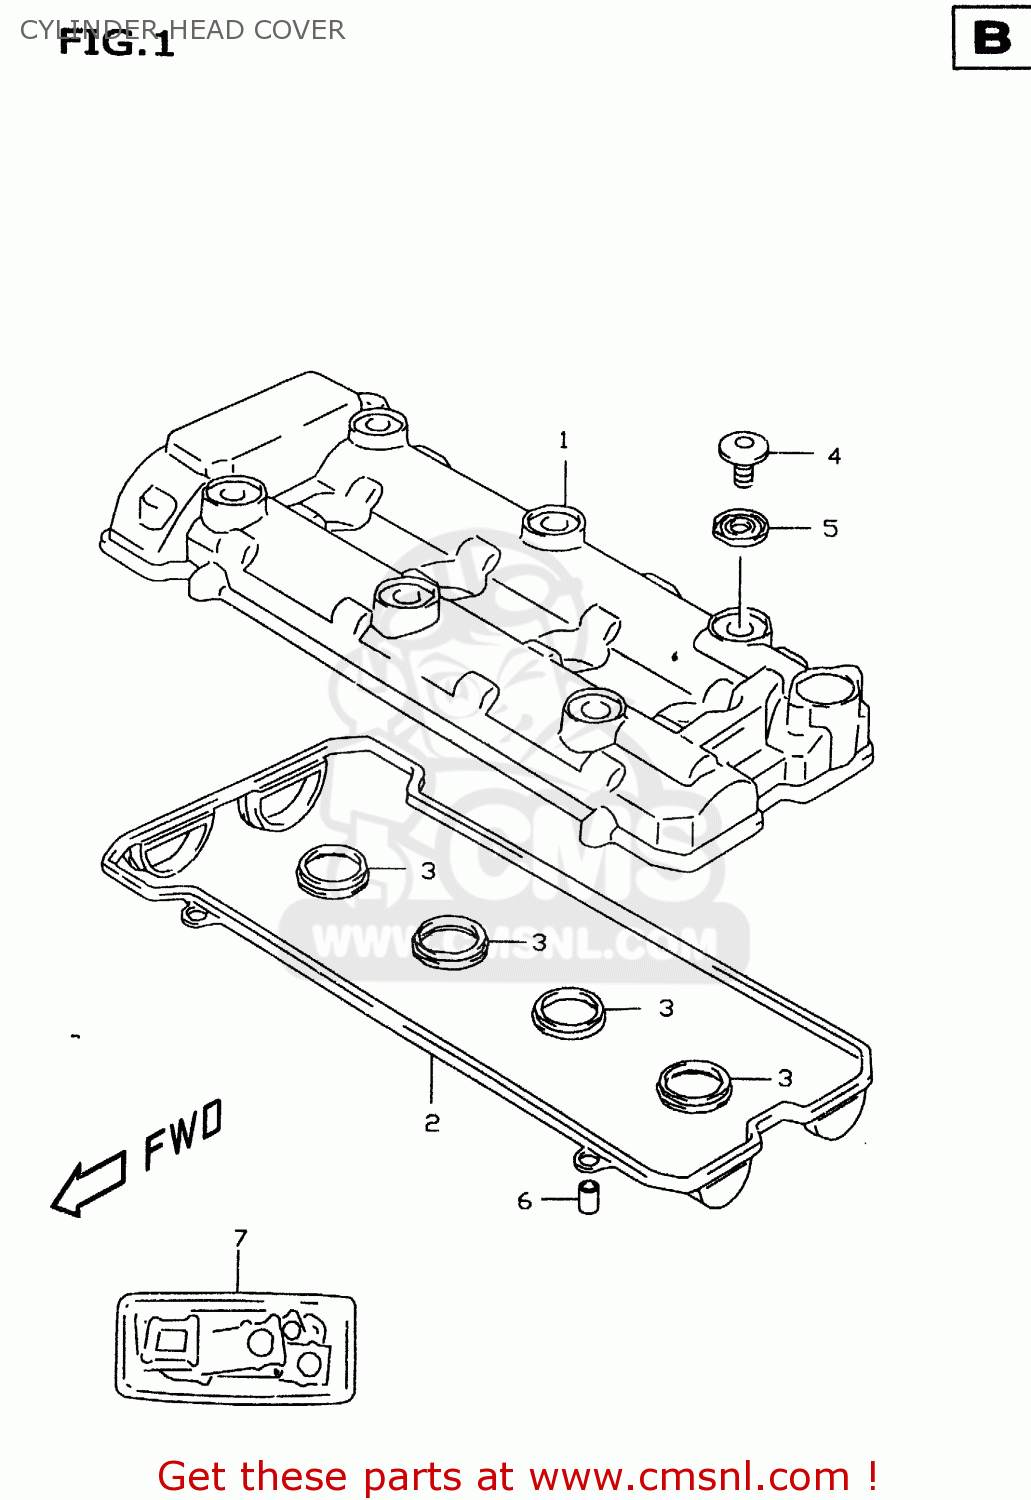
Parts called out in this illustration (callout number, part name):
1	COVER,CYLINDER HEAD
2	GASKET,CYL HEAD COVER NO.1
3	GASKET,CYL HEAD COVER NO.2
4	BOLT(7X17.5)
5	WASHER(10.6X25.5X2.3)
6	PIN(6.2X8X11)
7	GASKET SET (NAS)
